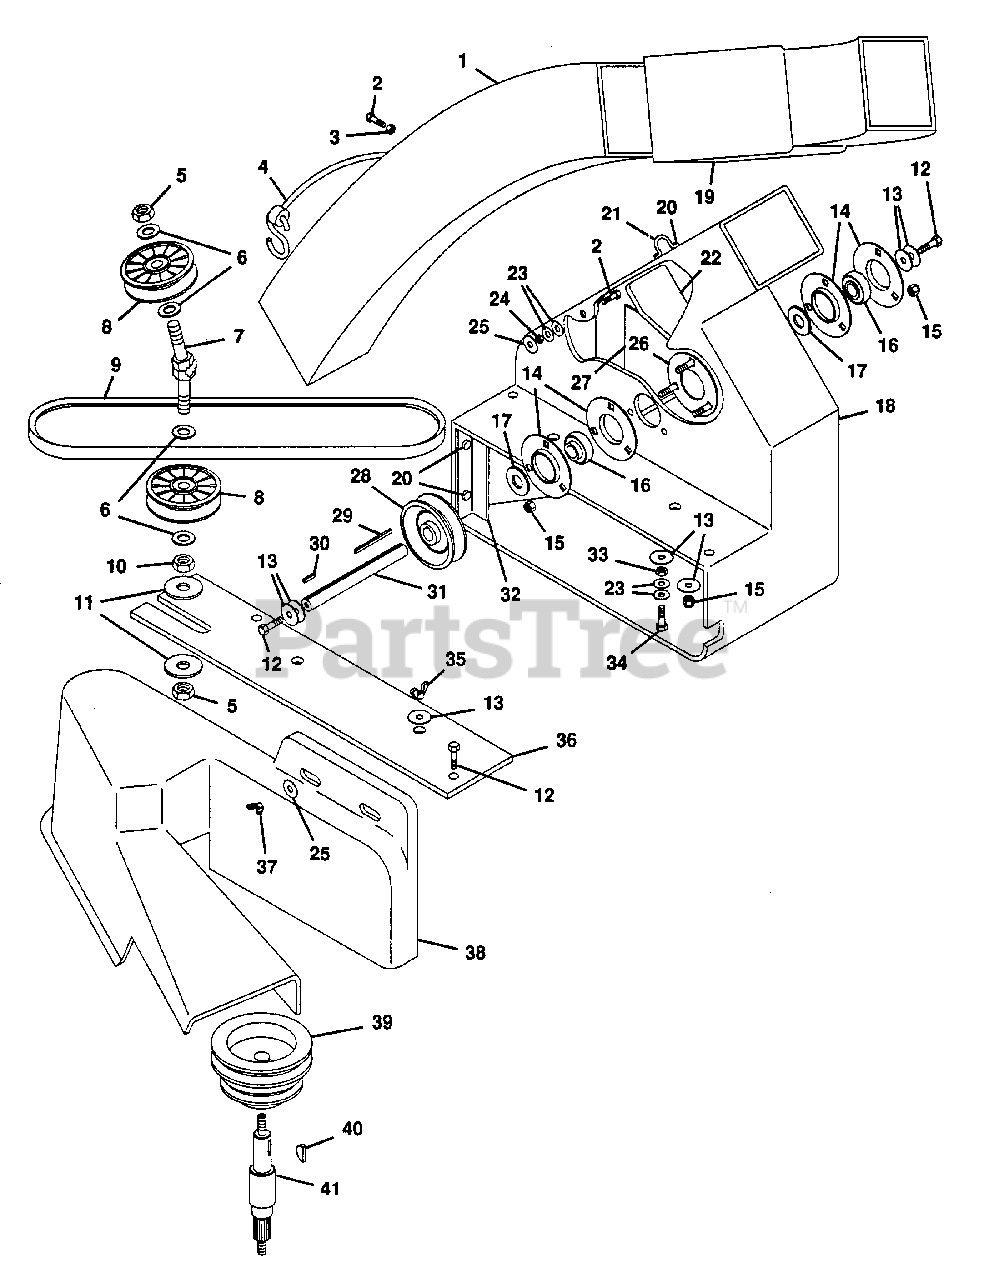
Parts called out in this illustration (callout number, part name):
1	Tube, Grass Catcher
2	Bolt, Hex 1/4-20x1.00
3	Nut, Lock 1/4-20
4	Assembly, Cord
5	Nut, Hex 5/8-11
6	Bearing, Thrust Race
7	Shaft, Double Idler
8	Idler, 4" with 5/8 Bore
9	Belt, AX-66
10	Nut, Jam 5/8-11 Hex
11	Washer, Flat .688x1.75x.134
12	Bolt, Hex 5/16-18x.75
13	Washer, Flat .344x1.25x.048
14	Flangette, Bearing
15	Nut, Lock 5/16-18
16	Bearing, 3/4 Shaft
17	Washer, Flat .812x1.469x.134
18	Shell, Blower
19	Chute, Short Curved
20	Rivet, Dome Head
21	Hook, Chute
22	Fan(Impeller)
23	Washer, Flat .312x.734x.065
24	Nut, Hex 1/4-20
25	Washer, Flat .375x1.125x.065
26	Weldment, Flangette
27	Weldment, Wall Support Plate
28	Sheave, Fan(4" Driven)
29	Key, Square .188x2.50
30	Key, Square .188x.50
31	Shaft, 3/4 Fan
32	Filler, Angle
33	Nut, Hex 5/16-18
34	Bolt, Hex 5/16-18x1.25
35	Nut, Wing 5/16-18
36	Plate, Blower Mounting
37	Nut, Wing 1/4-20
38	Guard, Belt(Large)
39	Pulley, Drive 50"
40	Key, Woodruff .250x1.00 Hrd #15
41	Shaft, Spindle
NS	Decal, Danger(HANDS)
NS	Decal, Danger(SHIELD)
NS	Decal, Danger
